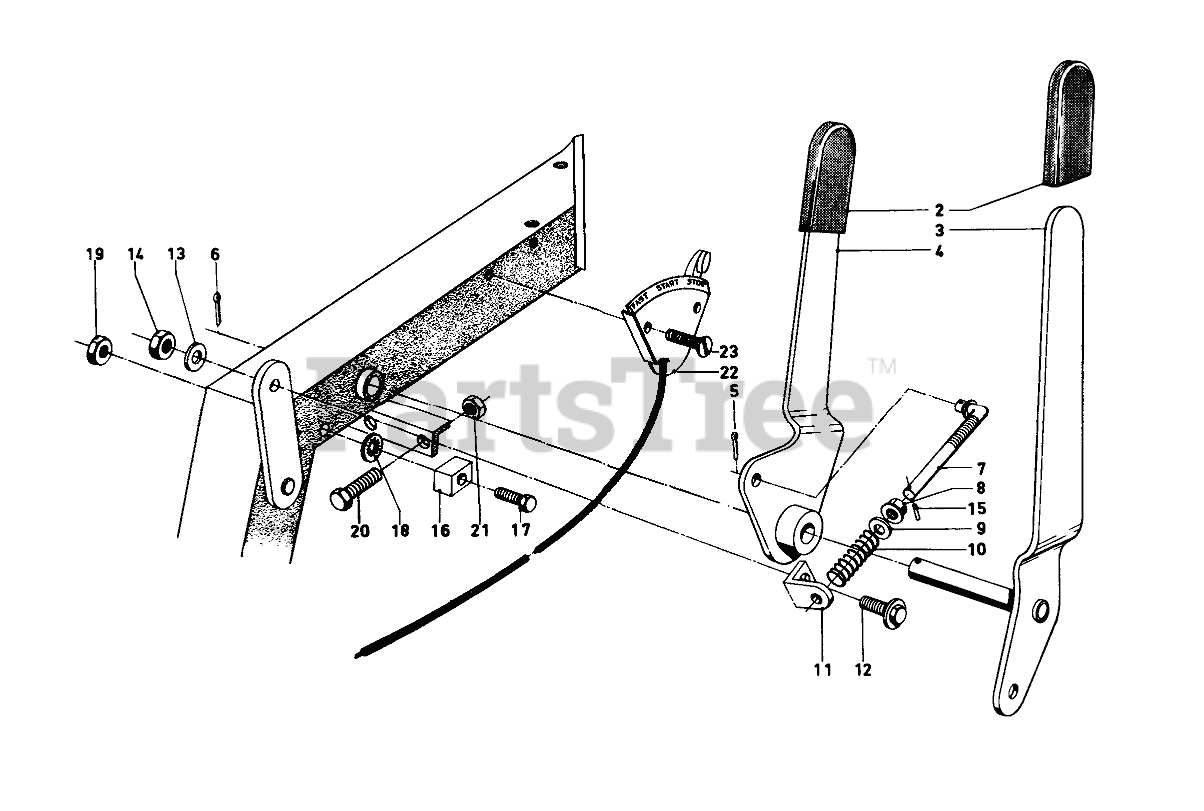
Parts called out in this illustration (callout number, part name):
3	Control, Traction
4	Control Reel
5	PIN-COTTER
6	PIN-COTTER
8	NUT-LOCK, INSERT
9	WASHER-FLAT
10	SPRING
11	PIVOT BRACKET
12	IDLER SHOULDER SCREW
13	WASHER-LOCK
14	NUT-JAM
15	PIN-ROLL, SLOTTED
16	REEL STOP
17	SCREW-HH
18	WASHER-LOCK
20	SCREW-HH
21	NUT-HEX
